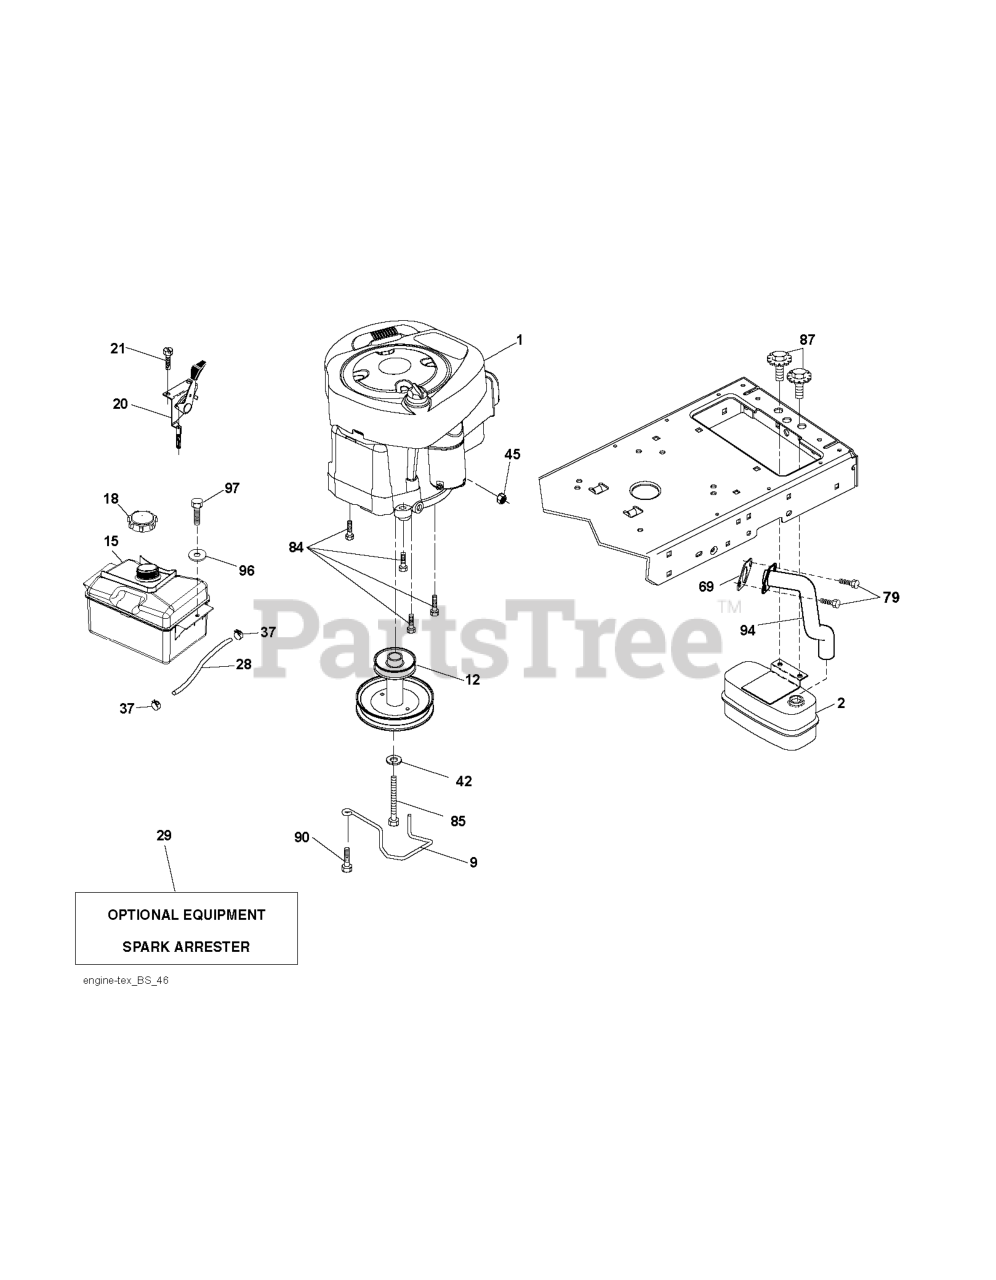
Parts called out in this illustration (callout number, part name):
2	MUFFLER.SINGLE.LRG.BRIGGS.KOHL
9	KEEPER.BELT.ENGINE.4.2
12	PULLY ENGINE
15	FUEL.TANK.ASM.NON-EPA
18	CAP ASM.FUEL.2.25"FR.
20	CONTROL.TH/CK.C.
21	SCREW.#10 X 0.750.BOS
28	LINE.FUEL.20
29	KIT.SPARK ARRESTOR 794945 B&S
37	HOSE CLAMP
42	LOCKWASHER
45	NUT
69	REPL BY 532 27 22-93
79	SCREW.SOCKET HD.5/16-1
84	SCREW.3/8-16
85	BOLT HEX 7/16-20X4-1/4"
87	BOLT.5/16-18UNCX3/4 W/SEMS.BLK
90	SCREW 3/8-16X1
94	RP.EXHAUST.TUBE.B&S.28/31
96	WASHER
97	SCREW HEXWSHR 1/4-20X3/4
